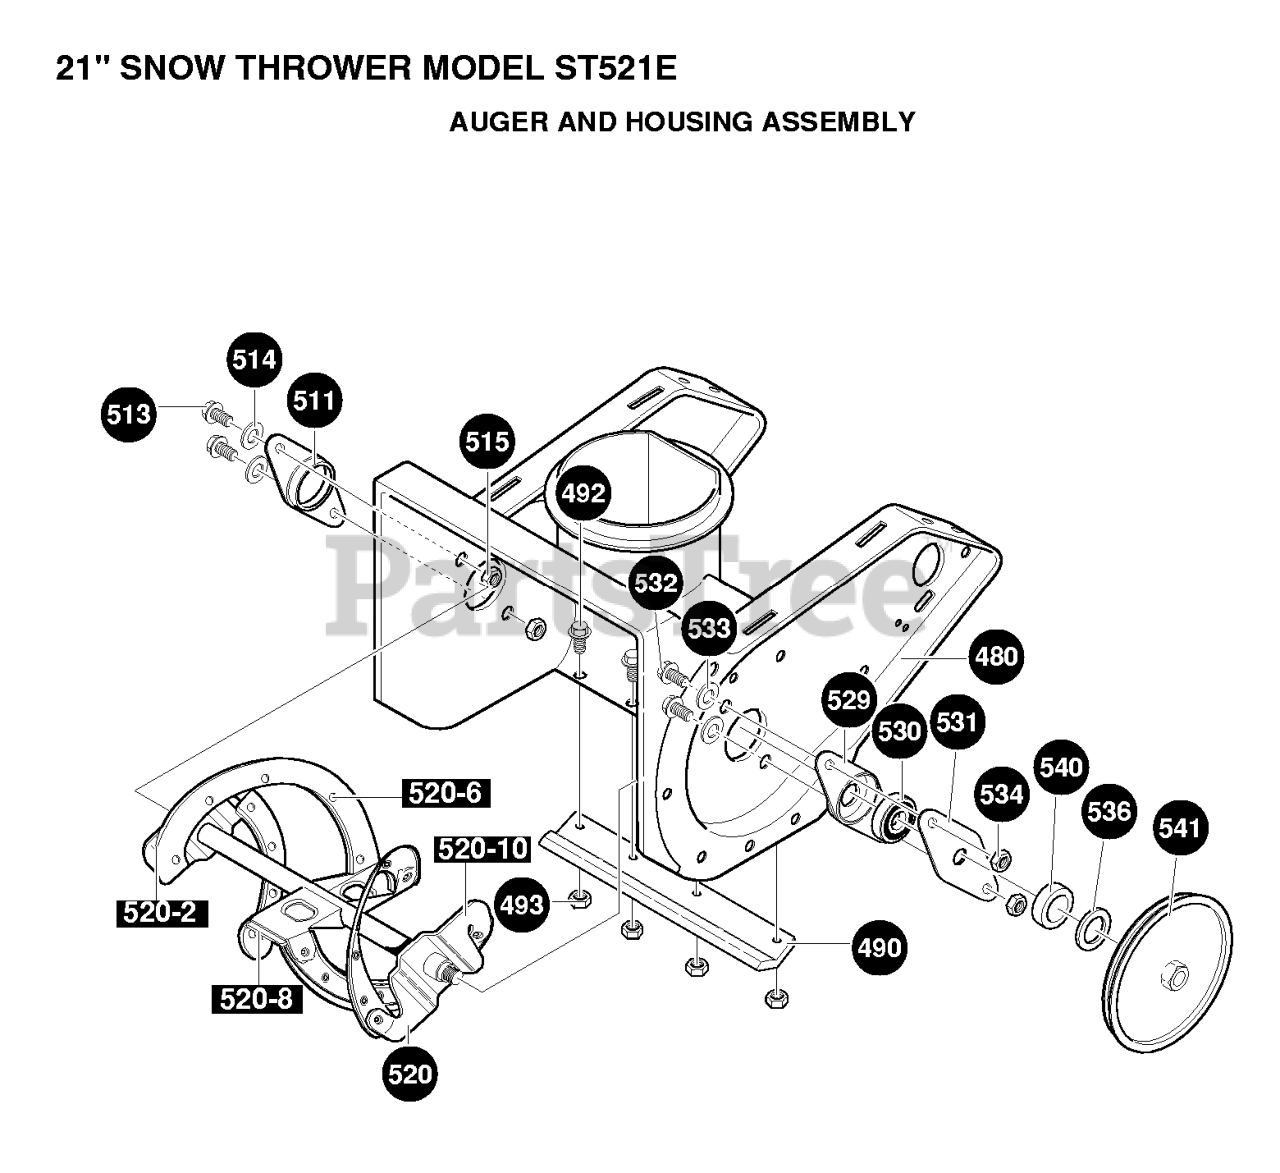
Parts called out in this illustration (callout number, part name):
480	HOUSING, AUGER
490	BLADE, SCRAPER 20.88 P
492	SCREW, 1/4-20X.63 SLTRMA
493	NUT 1/4-20
511	BEARING, FLANGE
514	WASHER, FLAT .281X .63X.
515	NUT 1/4-20
520	AUGER ASSY COMP 21"
520-2	BLADE, AUGER
520-6	RIVET, OVSET
520-8	AUGER, ASSY COMP
520-10	AUGER ASSY COMP 21"
529	BEARING RETAINER
530	BEARING, BALL
531	RETAINER, BRNG
532	SCREW, 1/4-20X .75 HHC
533	WASHER, FLAT .281X .63X.
534	NUT, 1/4-20 REGHEXCTRLK
536	WASHER,FLAT.640X1.25X.06
540	SPACER, SLEEVE
541	PULLEY, RIBBED 6" OD
